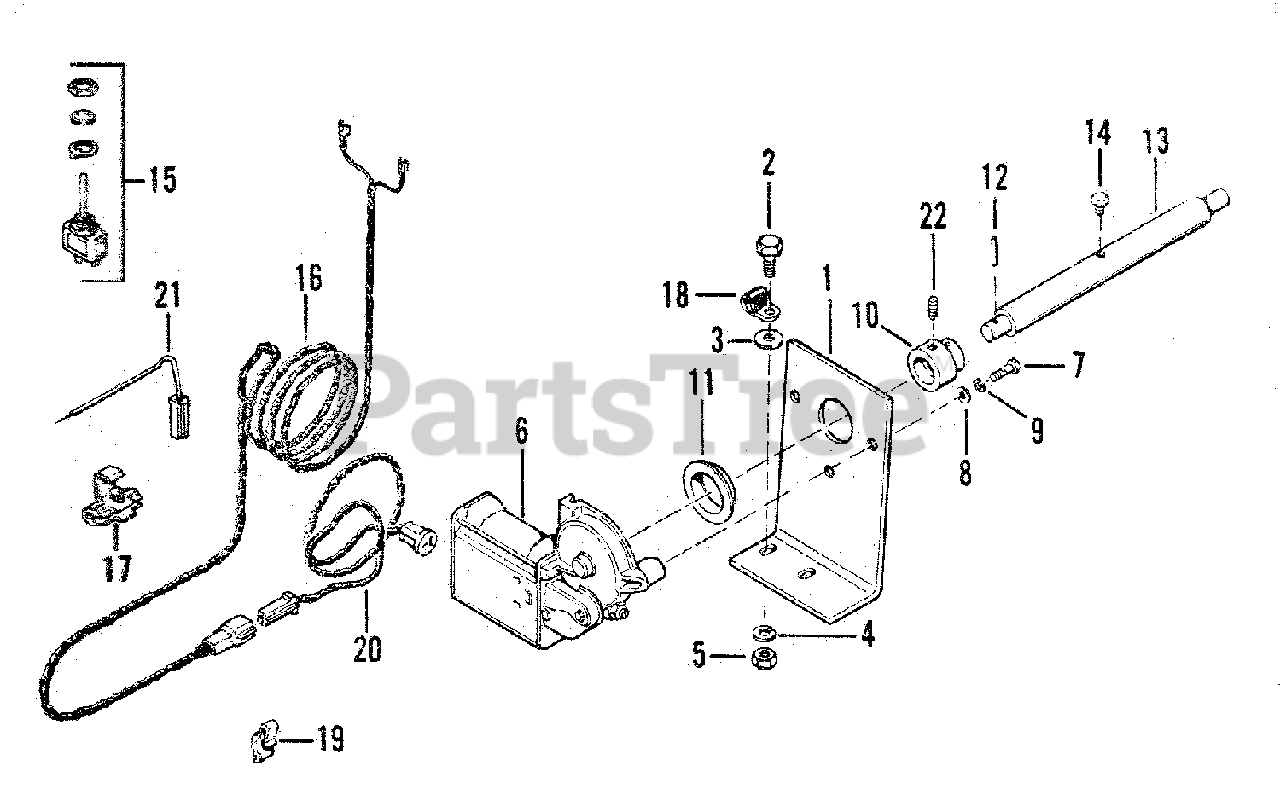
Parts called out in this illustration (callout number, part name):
1	BRACKET, Motor
2	CAPSCREW, Hex, 3/8"-16 x 1" Lg.
3	WASHER, Plain, 3/8"
4	WASHER, Lock
5	NUT, Hex, Full, 3/8"-16
6	MOTOR, Control
7	CAPSCREW, Hex, 1/4"-20 x 3/4" Lg
8	WASHER, Plain, 1/4"
9	WASHER, Lock, 1/4"
11	FLANGE, Bearing
12	PIN, Roll, 3/16" x 1-1/4"
13	ROD, Control
14	SCREW, Taptite, 1/4"-20 x 3/8" Lg.
15	SWITCH, Spout Control
16	WIRING ASSEMBLY (Switch)
19	CLIP, Cable
20	HARNESS ASSEMBLY (Motor)
21	WIRE (Switch To Pos.)
22	SCREW, Set, No. 10-24 x 3/8" Lg.
